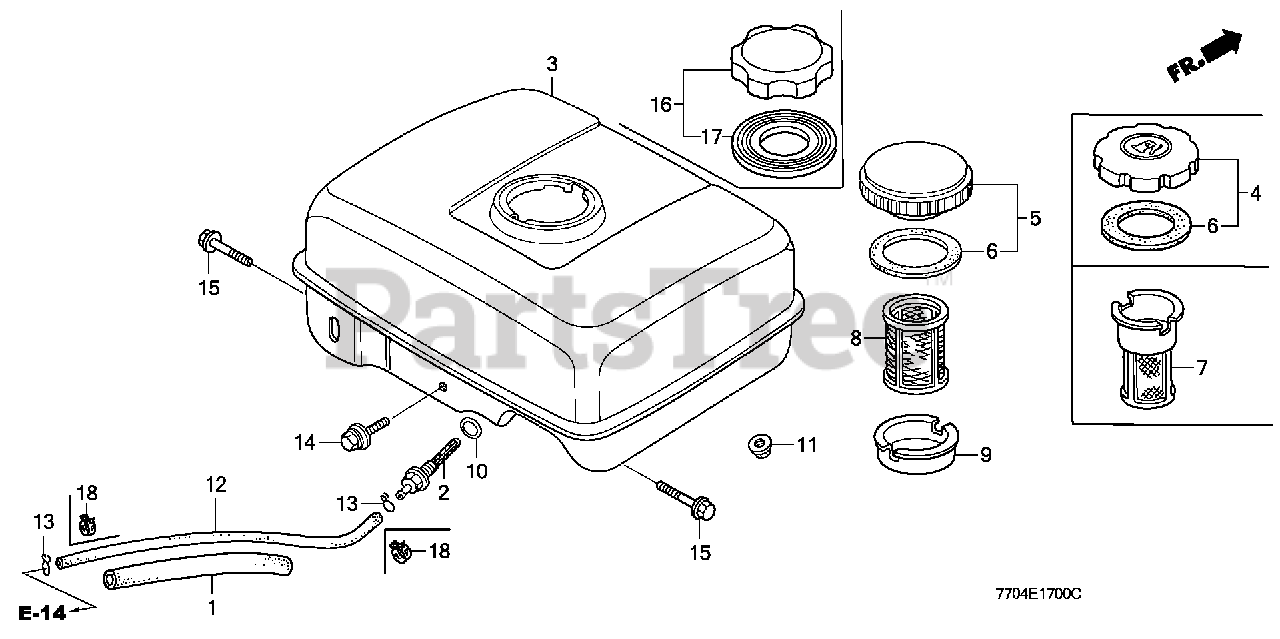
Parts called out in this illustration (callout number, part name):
1	RUBBER, SUPPORTER (107MM)
2	JOINT, FUEL TANK
3	TANK, FUEL *R280* (POWER RED)
4	CAP, FUEL FILLER (BLACK)
6	GASKET, FUEL FILLER CAP (39X58X3)
7	FILTER, FUEL (N/A: USE FILTER 17672-887-791 + FILTER HOLDER 17673-893-000)
10	O-RING (14MM) (ARAI)
10	O-RING (14MM) (NOK)
11	NUT, FLANGE (6MM)
12	BULK HOSE, FUEL (4.5X3000) (4.5X140)
13	CLIP, TUBE (B8)
14	BOLT, FLANGE (6X25)
